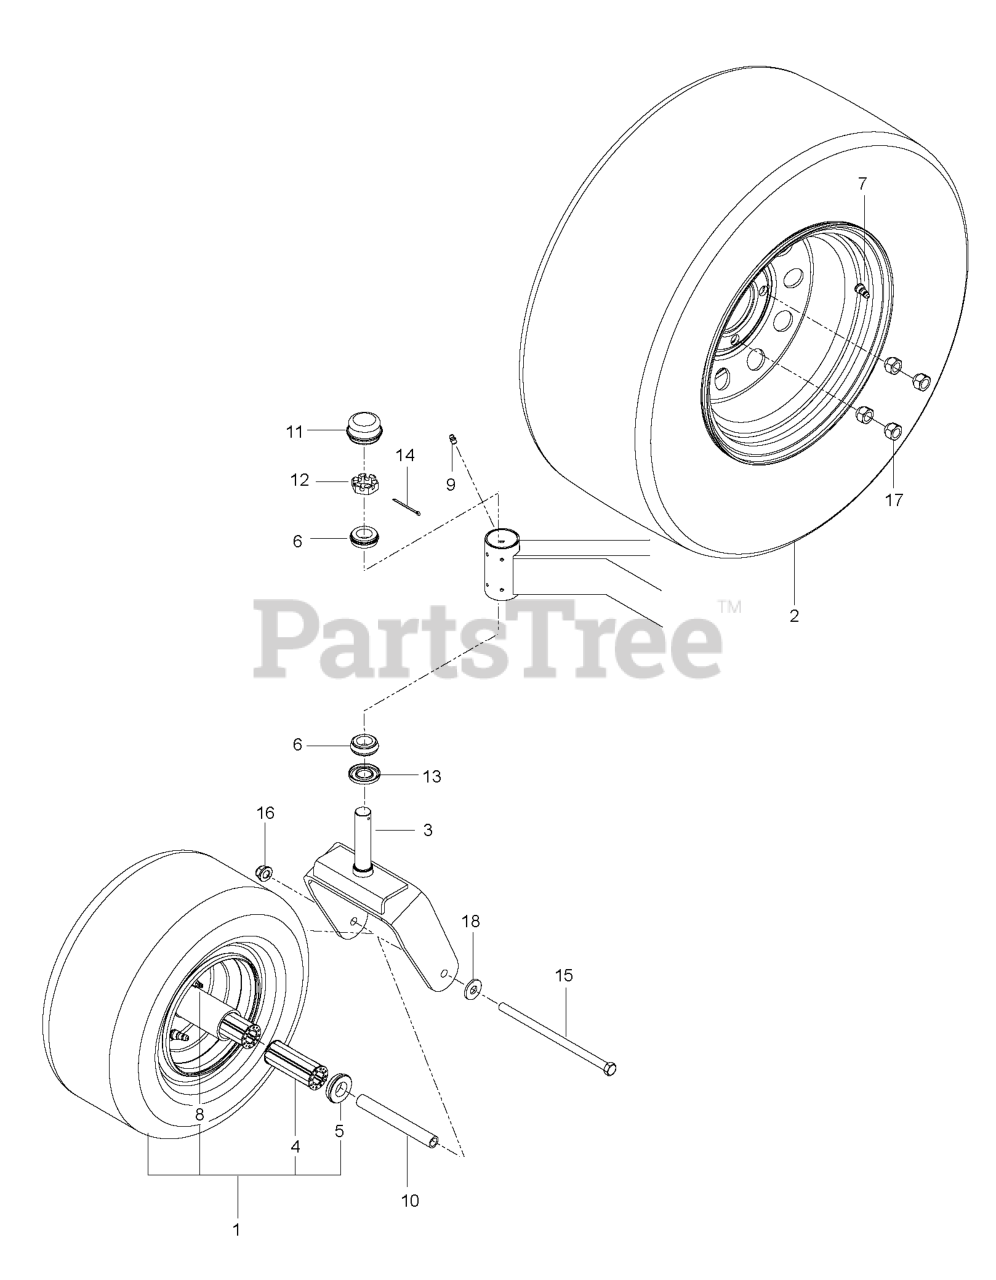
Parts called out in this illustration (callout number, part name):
1	TIRE.ASSEM.CASTER.13X6.5-6.SIL
2	RP WHEEL.ASM.23X10.5-12.TURFMA
3	YOKE.CASTER.ORANGE
4	ROLLER BEARING-CAGED 3 1/4'
5	BEARING RETAINER
6	TAPERED ROLLER BRG
7	VALVE STEM TR-412
8	ZERK
10	SPACER, PIVOT
11	GREASE CAP
12	NUT 1"C HEX SLOTTED
14	COTTER PIN 1/8 X 2
15	HEX SCREW 1/2-13 X 9.5 GR5
16	NUT, 1/2-13 HEX FLG NYLOC ZD
17	LUG NUT 1/2F
18	WASH USS FLAT 1/2
